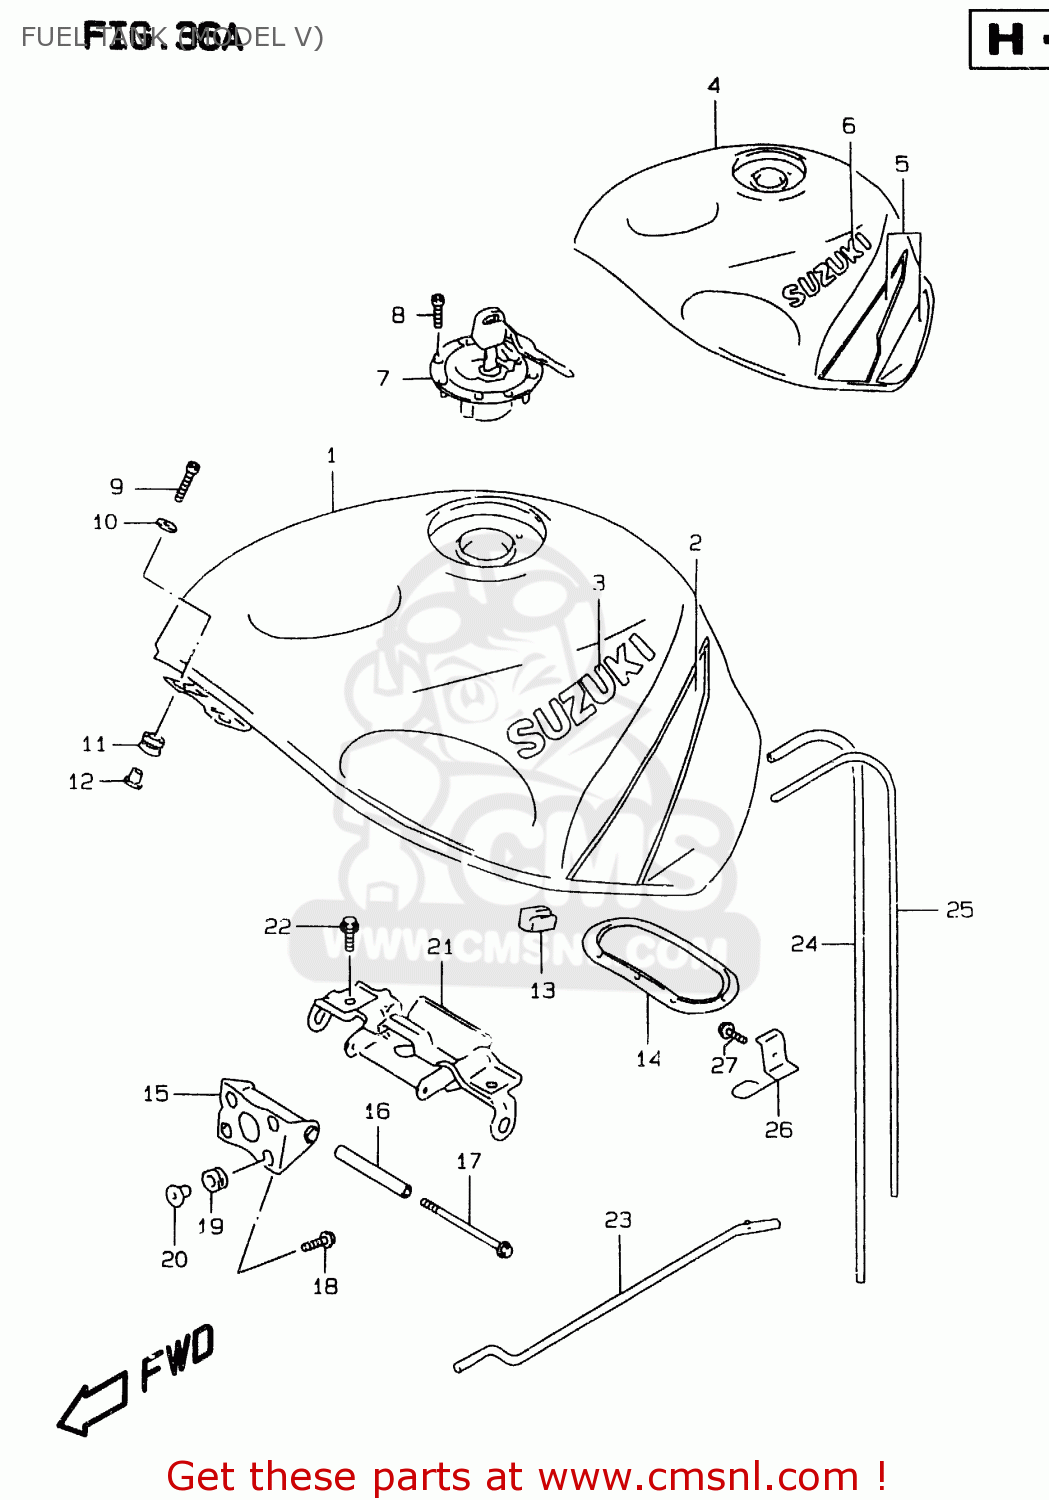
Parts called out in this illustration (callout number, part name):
1	TANK ASSEMBLY,FUEL
2	TAPE SET,FUEL TANK
3	EMBLEM,FUEL TANK (CARBON)
4	TANK ASSY,FUEL
5	TAPE SET,FUEL TANK
6	EMBLEM,FUEL TANK
7	CAP SET,FUEL TANK
8	BOLT(5X20)
9	SCREW(6X25)
10	WASHER
11	CUSHION
12	WASHER
13	CUSHION,FUEL TANK SIDE
14	PACKING,FUEL PUMP
15	BRACKET COMP,FUEL TANK
16	SPACER,FUEL TANK,REAR
17	BOLT
18	BOLT 6X20,WITH PLAIN WASHER
19	CUSHION
20	WASHER
21	BRACKET,FUEL TANK NO.2
22	BOLT
23	STAY,FUEL TANK
24	HOSE(5X8.2X600)
25	HOSE(7X10.2X600)
26	GUIDE COMP,DRAIN HOSE
27	BOLT
